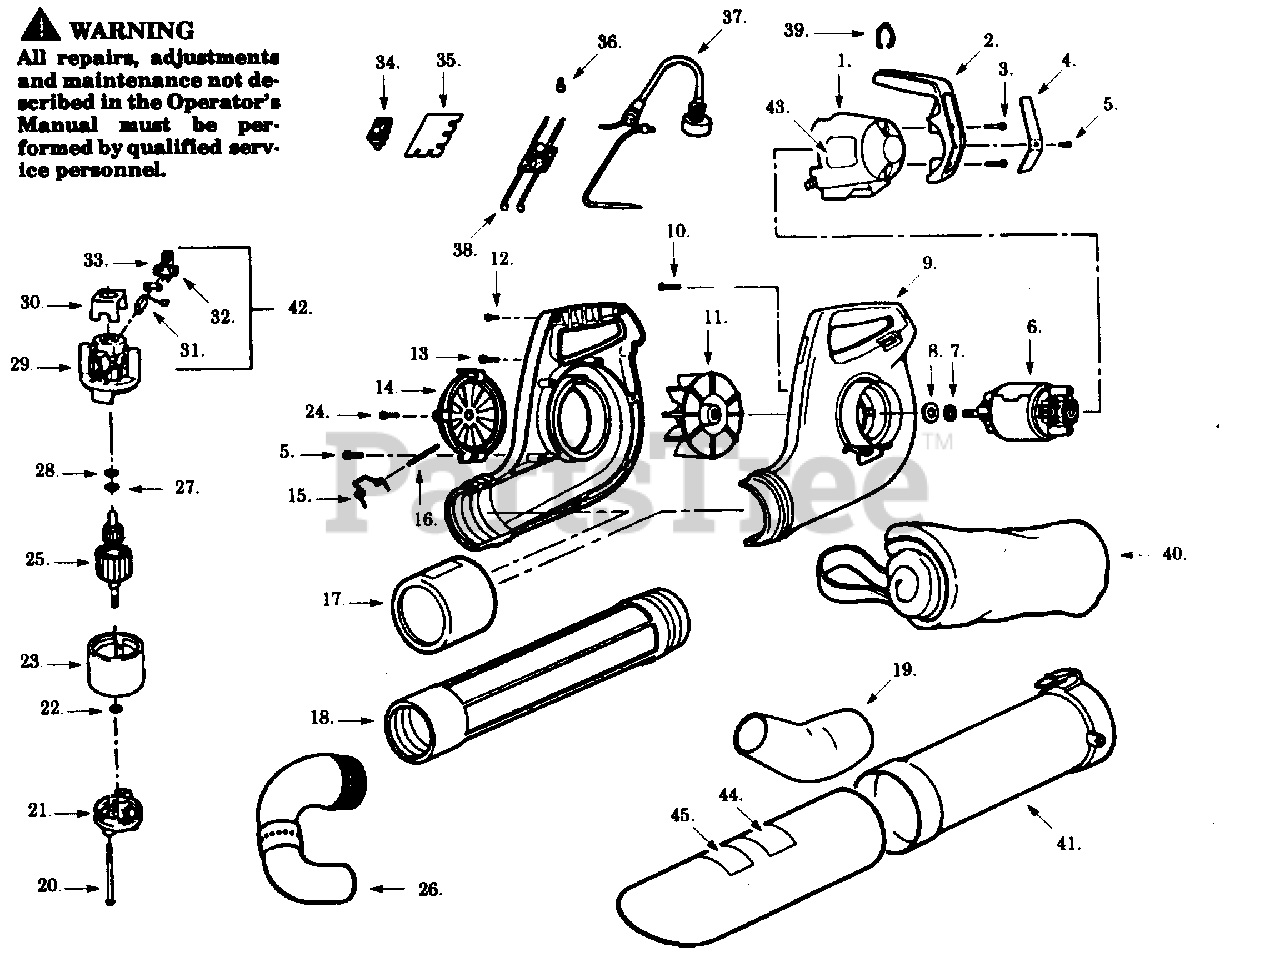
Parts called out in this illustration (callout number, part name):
1	Motor Cover
7	Retaining Ring
9	L.H/R.H. Housing
11	Impeller Ass'y.
14	Inlet Cover
16	Hinge Pin
17	Ferrule Sleeve
18	Outlet Tube
19	Curved Nozzle
21	Endbell Ass'y. (Drive)
23	Field Ass'y.
25	Armature Ass'y.
26	Nozzle Ass'y.
29	Endbell Ass'y. (Brush)
30	Insulator
32	Brush Spring
33	Brush Holder
34	On-Off Switch Ass'y.
35	Mounting Board
36	Wire Nut
37	Power Cord Ass'y.
38	P.C. Board Ass'y.
40	Vacuum Bag
41	Vacuum Tube
42	Brush Kit (Incl. 31,32,33)
43	Motor Cover Label (Not a serviceable part)
44	Name Plate Label
45	Warning Label
